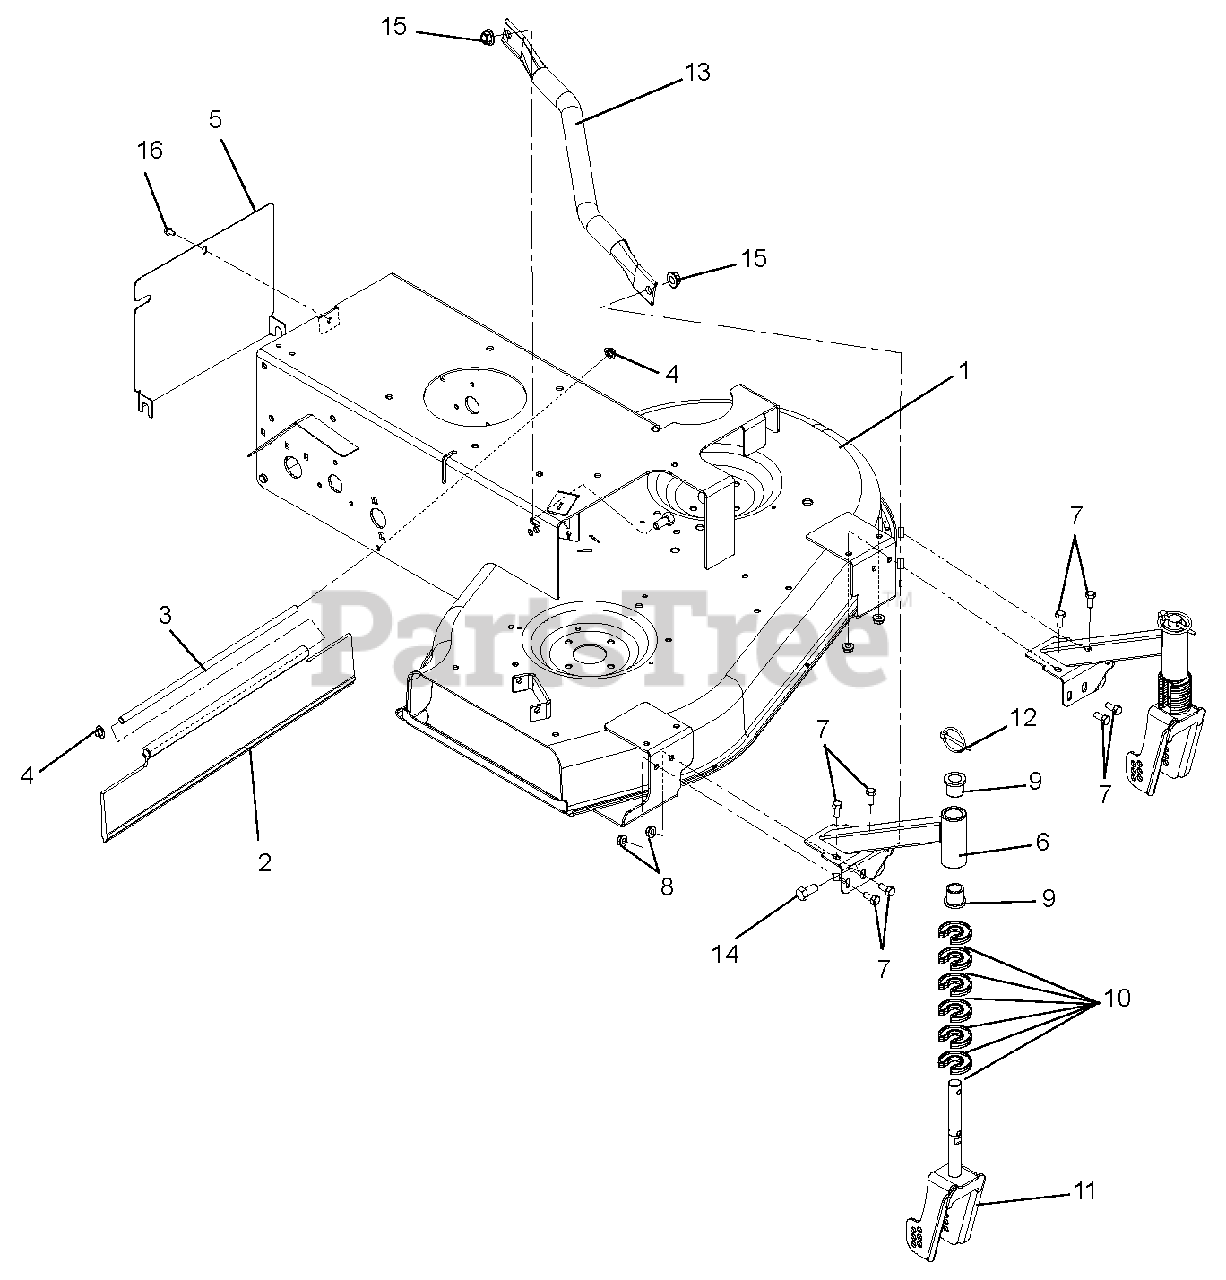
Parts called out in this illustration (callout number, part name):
1	Chassis, Wide Area Walk
2	Guard, Rear Swivel
3	Rod, Trailing Shield
4	Nut, Push .312 Dia. PAL
5	Cover, Rear Chassis
6	Weldment, Caster Arm
7	Bolt, Hex .31-18 x .75
8	Nut, Locking Top Flange .31-18
9	Bushing, Flange .75 x .75 x 1.0
10	Clip, HOC Fixed
11	Fork, WAW Caster
12	Pin, Lynch .25 x 1.25
13	Strap, Frame Reinforcing
14	Bolt, Hex .38-16 x .75
15	Nut, Locking Top Flange .38-16
16	Screw, Tapping .25-20 x .50
